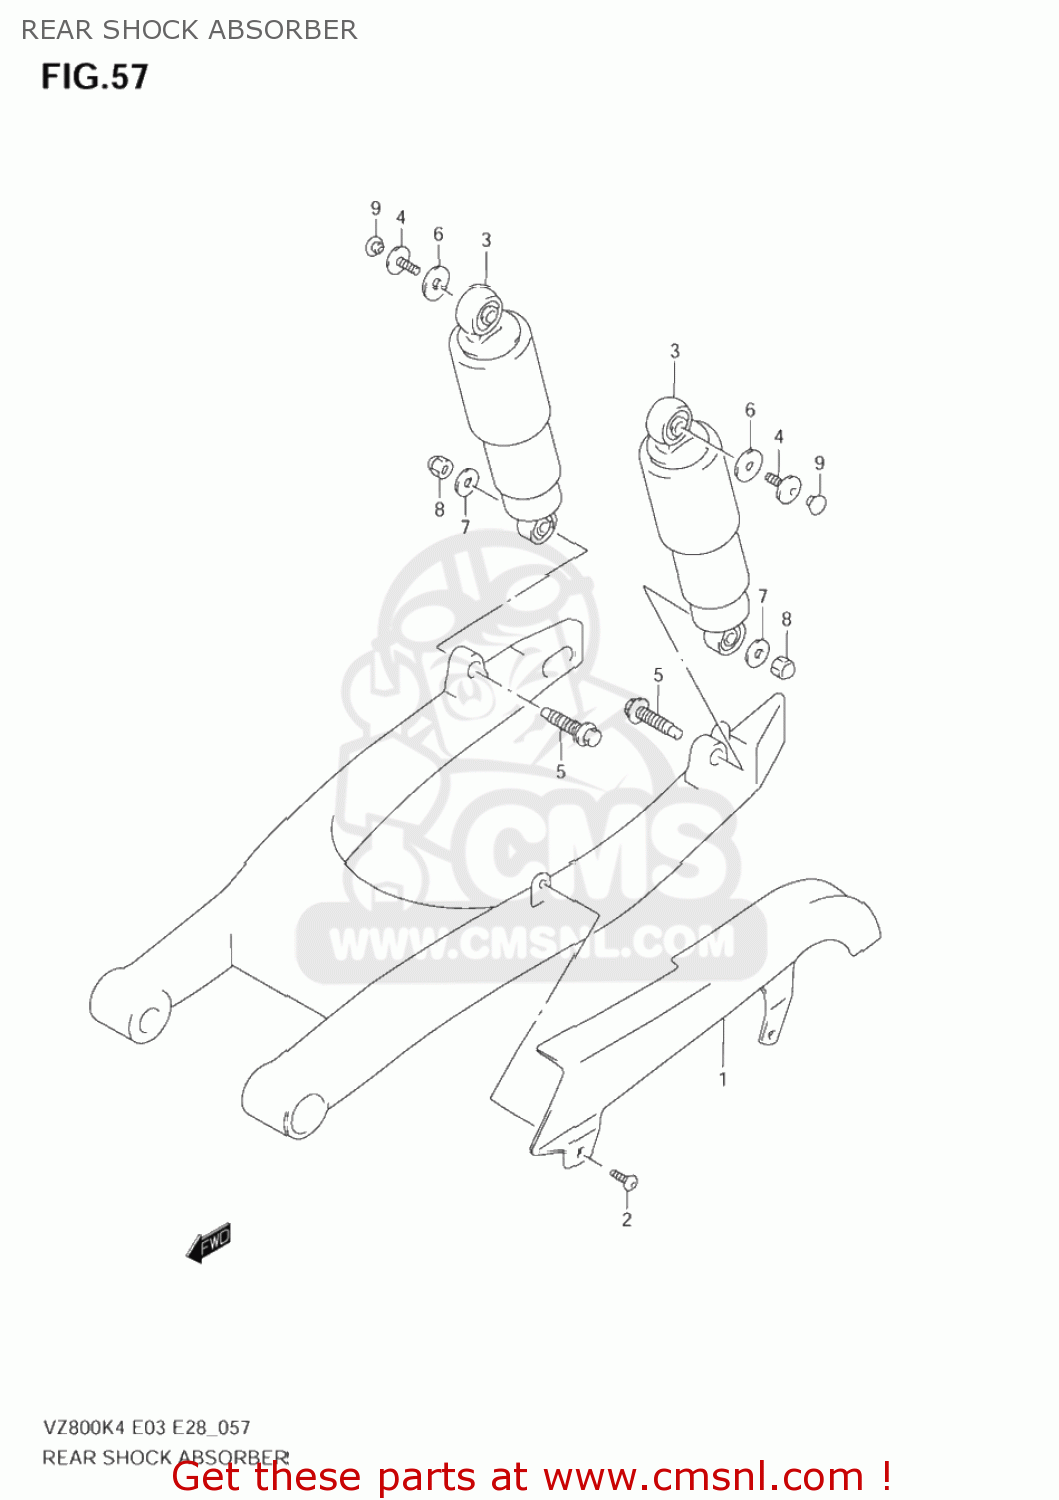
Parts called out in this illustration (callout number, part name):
1	CASE,CHAIN
2	SCREW
3	ABSORBER ASSY,RR SHOCK
4	BOLT(8X20)
5	BOLT,RR SHOCK ABSORBER
6	WASHER (8.5X30X2.3)
7	WASHER(10.5X28X2.3)
8	NUT
9	CAP(OD:14.5)
